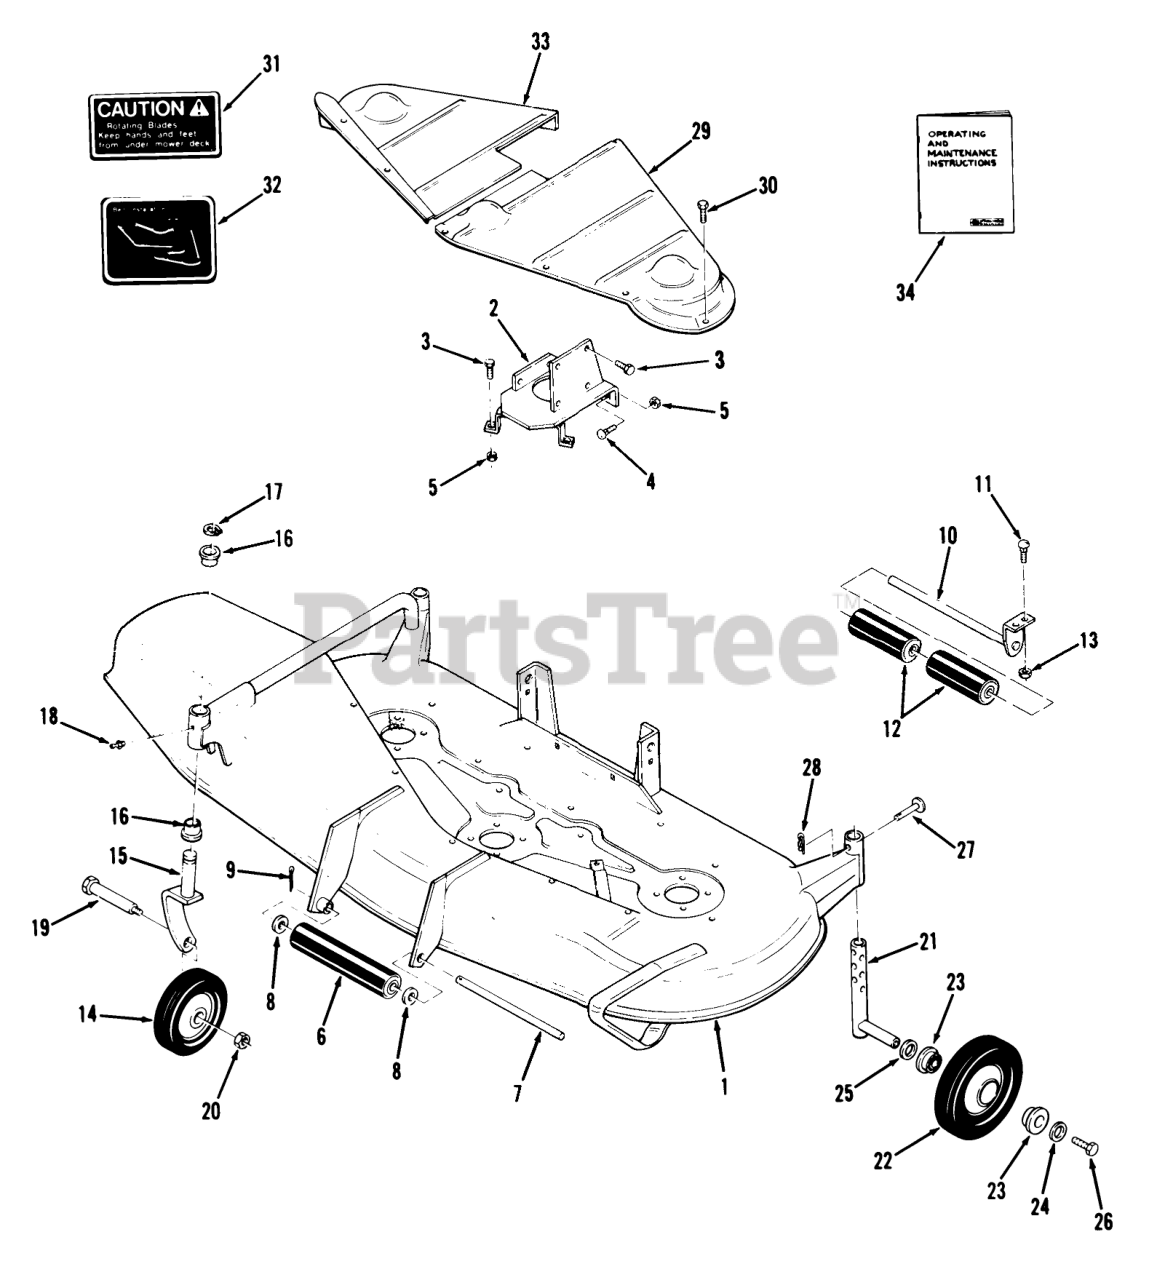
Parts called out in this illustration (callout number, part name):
1	Mower Deck
2	Gear Box Base
3	Bolt
4	Bolt-Carriage
5	Nut
6	ROLLER-FRONT
7	SHAFT-FRONT ROLLER
8	WASHER
9	Cotter Pin5/32 X 2
10	Rear Roller Bracket
11	Bolt
12	Rear Roller, 7"
13	Nut
14	Wheel
15	Caster Arm
16	BEARING
17	RING-SNAP, EXTERNAL
18	Zerk
19	BOLT-SHOULDER
20	Nut
21	Gauge Wheel Arm
22	Gauge Wheel (with Bearings)
23	Ball Bearing
24	Collar
25	WASHER
26	Bolt
27	CLEVIS PIN
28	Hairpin Cotter
29	L.H. Drive Shield
30	Bolt
31	Caution Decal
32	"Belt" Decal
33	R.H. Drive Shield
34	Operating and Maintenance Instructions
